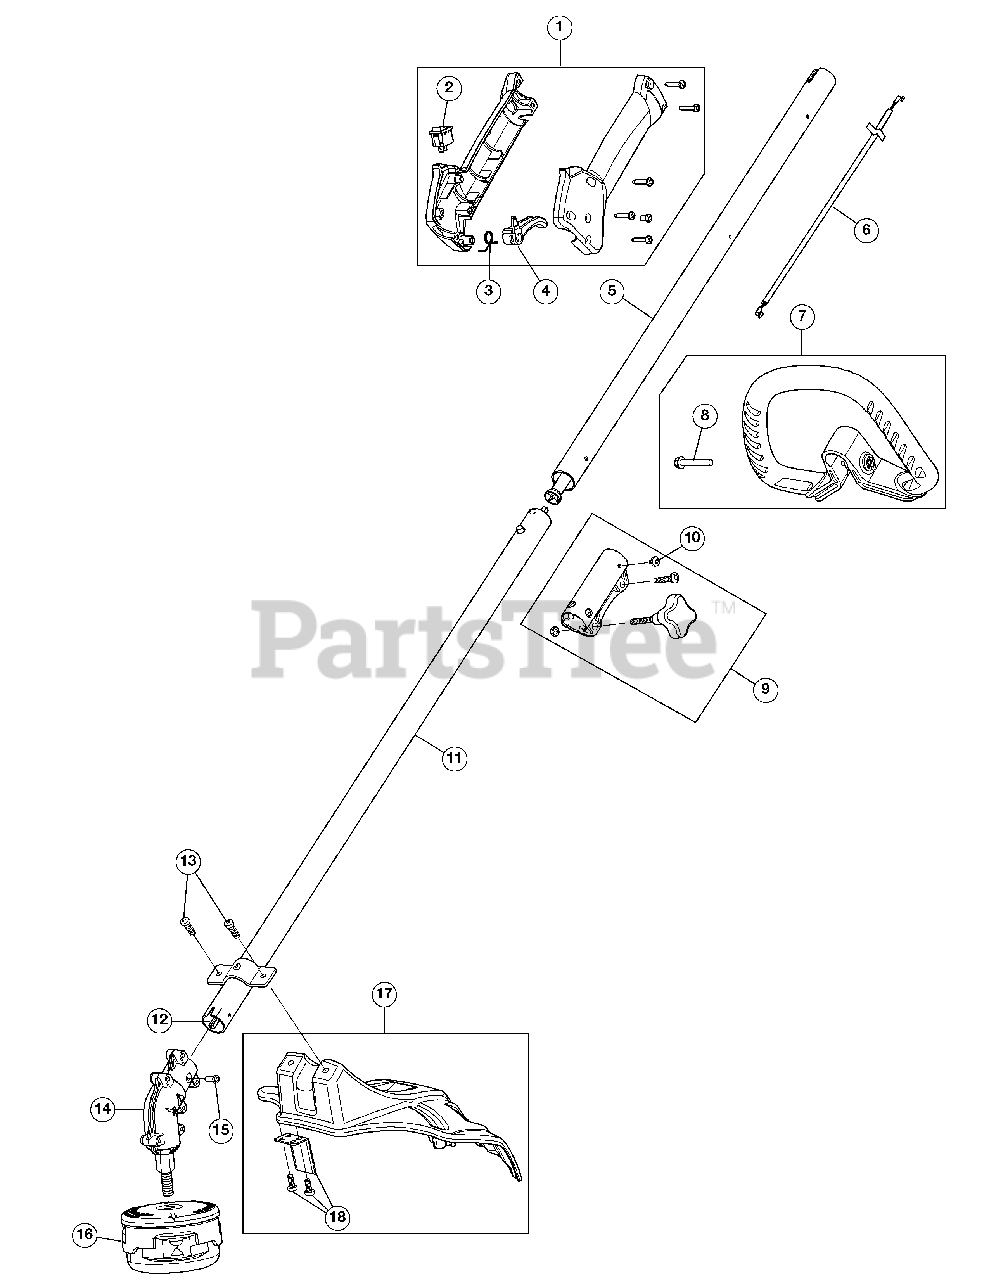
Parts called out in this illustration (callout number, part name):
1	Throttle Housing Assembly (Incl. 2 - 4)
2	Switch Assembly
3	Throttle Trigger Spring
4	Throttle Trigger
5	Upper Drive Shaft Housing Assembly
6	Throttle Cable Assembly
7	Deluxe D-Handle Assembly (Incl. 8)
9	Split Boom Coupler (Incl. 10)
11	Lower Drive Shaft Housing Assembly
12	Lower Flexible Drive Shaft
13	Shield Mounting Screws
14	Gear Box Assembly (Incl. 15)
15	Anti-Rotation Screw
16	Cutting Head Assembly
17	Shield Assembly (Incl. 18)
18	Blade Assembly
